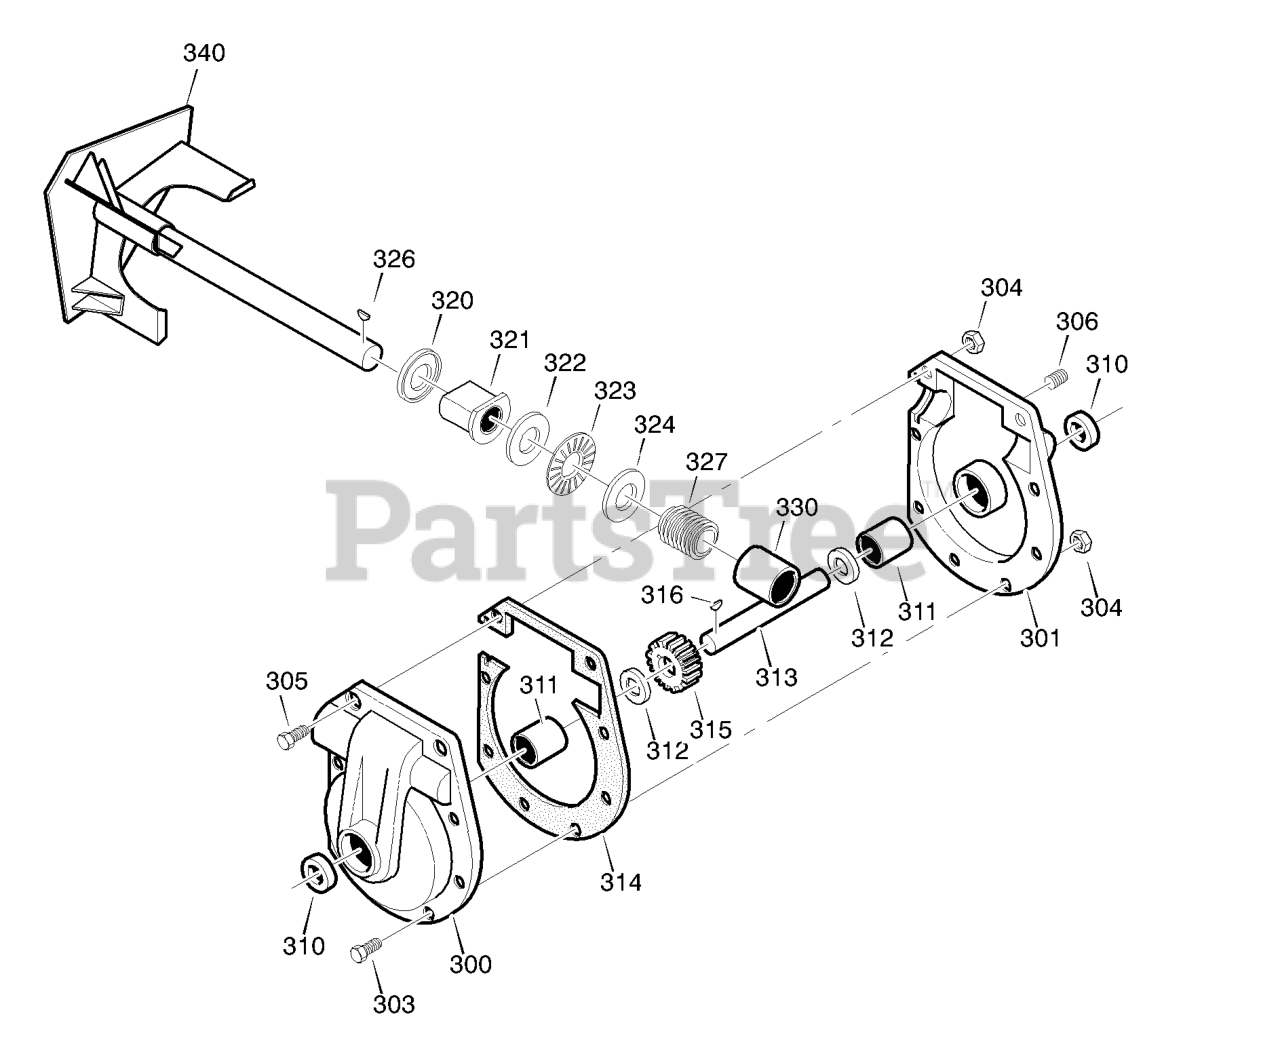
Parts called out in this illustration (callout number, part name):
300	CASE, GEAR, RH
301	CASE, GEAR, LH
303	SCREW, 5/16-24 x 1.00
304	NUT, 5/16-24
305	SCREW 5/16-24 X 1.50
306	PLUG, PIPE 1/4-18
310	SEAL, OIL
311	BEARING, SLEEVE
312	WASHER, FLAT
313	SHAFT, AUGER OUTPUT
314	GASKET, GEAR BOX
315	WORM GEAR
316	KEY, WOODRUFF #91
320	RING, QUAD
321	BEARING, FLANGE
322	WASHER, FLAT
323	BEARING, ROLLER
324	WASHER, FLAT
330	BEARING, SLEEVE
340	IMPELLER
